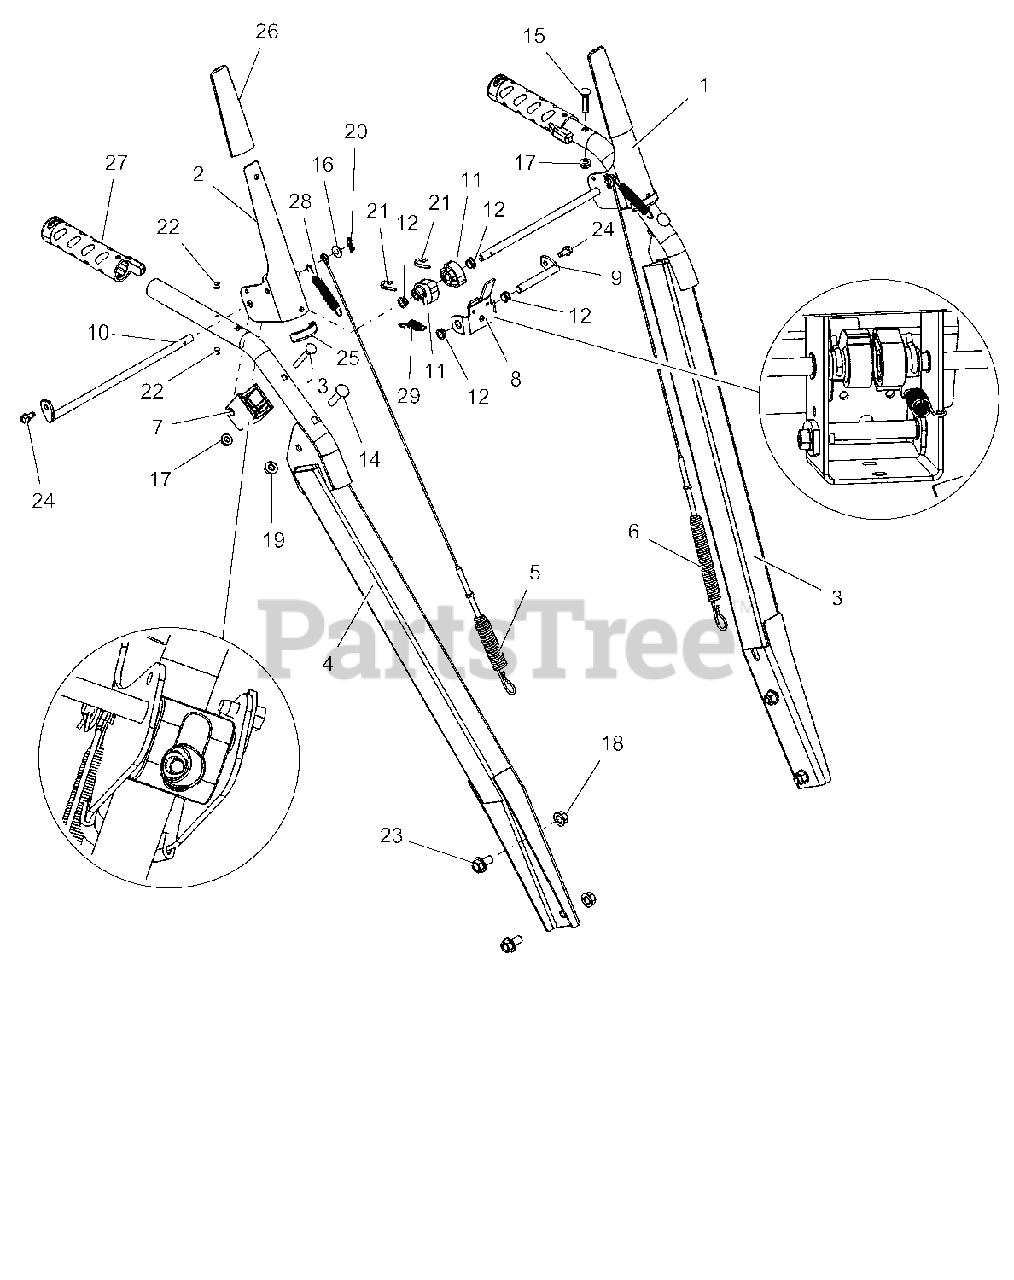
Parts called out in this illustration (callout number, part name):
1	LEVER, CLUTCH-LH
2	LEVER, CLUTCH-RH
3	HANDLEBAR, HEAVYDUTY-PRO LH
4	HANDLEBAR, HEAVYDUTY-PRO-RH
5	CABLE, AUGER (DELUXE & PRO)
6	CABLE, UPPER TRACTION
7	BLOCK, CLUTCH PADDLE
8	BRACKET, INTERLOCK ARM
9	ROD, INTERLOCK PIVOT
10	ROD, PADDLE MOUNT - PRO
11	CAM, INTERLOCK
12	BUSHING, POLYLINER-.38 SNAPIN
13	BLT-RDHDXLSQNK .25-20X2.0 G5YZ
14	BLT-RDHDSQNK .31-18X1.50 G5YZ
15	BLT-RDHDXLSQNK.25-20X1.25 G5YZ
16	WSHR-FL-STL.281X.62X.065 YWZC
17	NUT-LK-CTR-FLG .25-20 YWZC
18	NUT-LK-TOP-FLG .38-16 YWZC
19	NUT-LK-TOP-FLG .31-18 YWZC
20	PIN-HAIR INT .06X.18X.77
21	PIN, SPRING CLIP
22	RVT-POP #43 .125X.313 STL ZINC
23	BLT-SERHFWH .38-16X.75 YWZC
24	SCR-TAP .25-20X.50 HWH TR YWZ
25	EDGING, CLUTCH PADDLE - 2.00"
26	SLEEVE, CLUTCH PADDLE-GRAY
27	GRIP,HEATED HANDLE-GRAY
28	SPRING, EXTENSION
29	SPRING-EXT .047X.438X1.45
